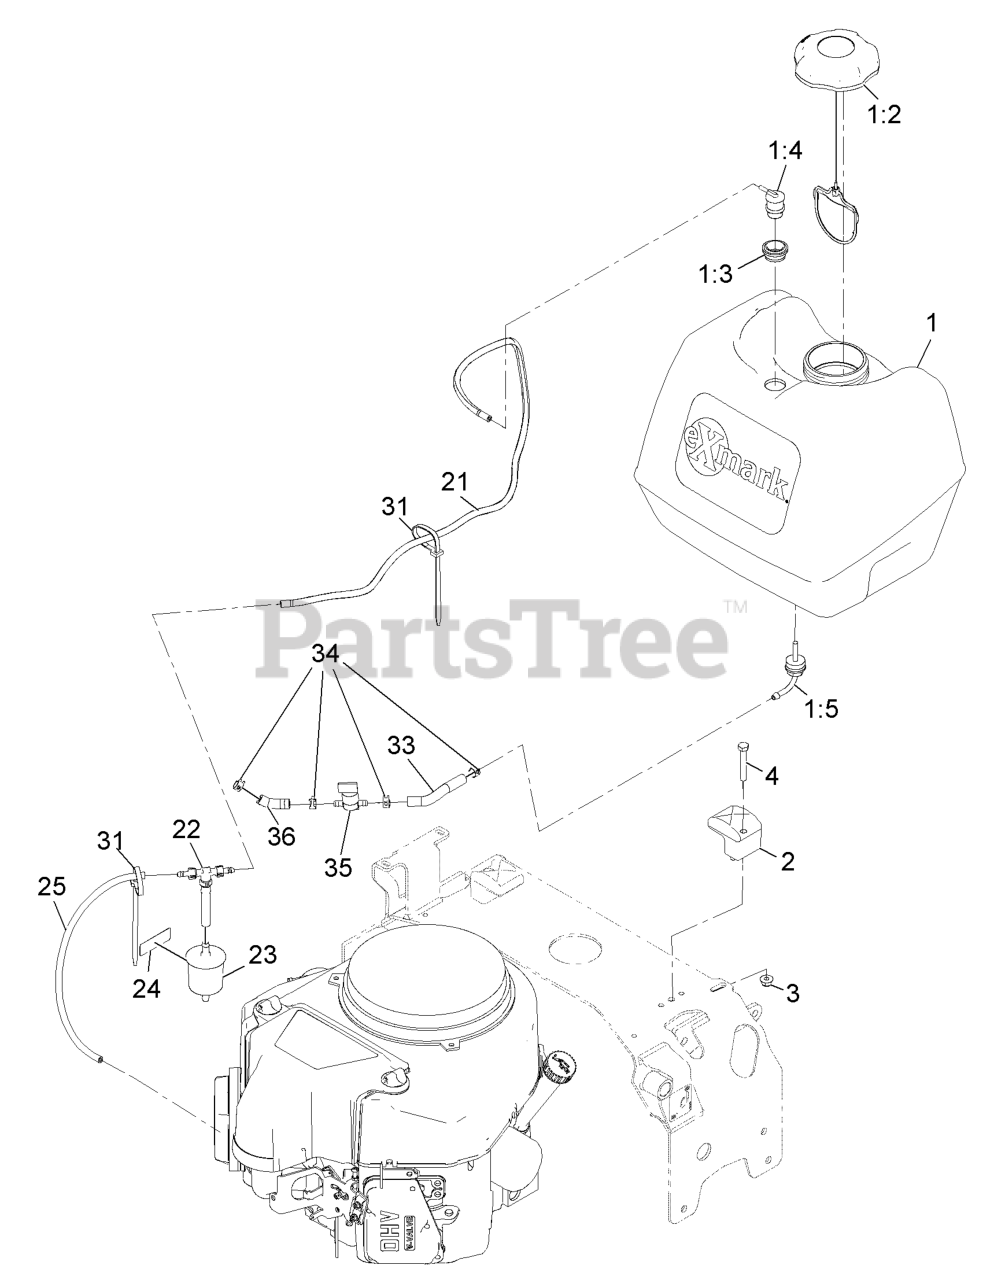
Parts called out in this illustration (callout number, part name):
1	ASM, FUEL TANK
1:3	GROMMET
1:4	VALVE-VENT, FUEL
1:5	FITTING-FUEL, BULKHEAD
3	NUT-HF, NI
4	SCREW-HH
21	HOSE, EMISSIONS
22	TEE AND CHECK
23	FILTER-FUEL
24	DECAL-FILTER, EMISSIONS
25	HOSE-FUEL
31	TIE-PLASTIC
33	HOSE-FUEL
34	CLAMP-HOSE
35	VALVE-FUEL
36	HOSE-FUEL
